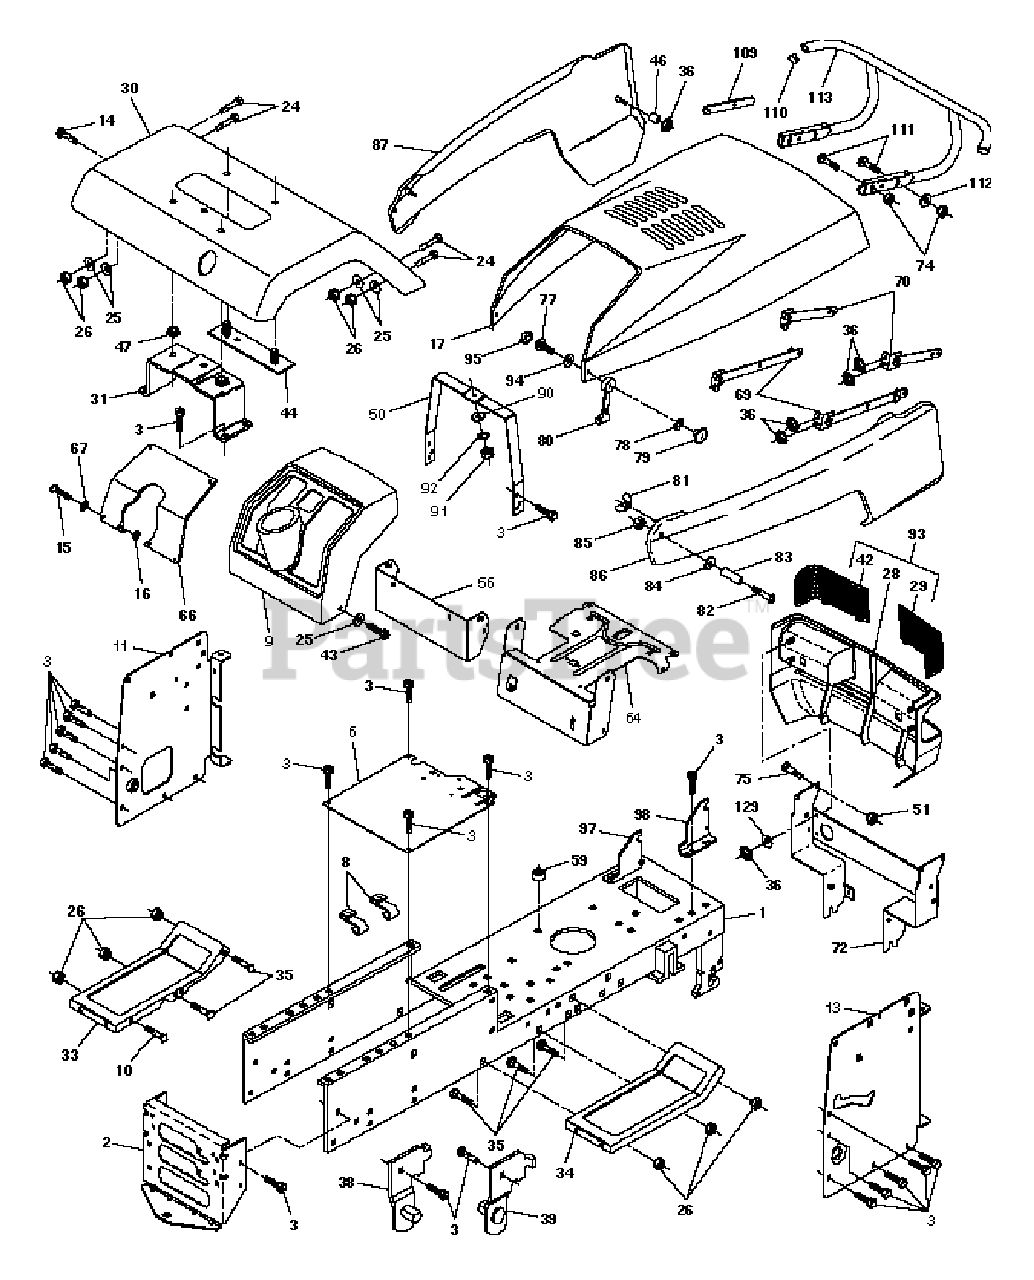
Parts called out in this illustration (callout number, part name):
1	Chassis WLDMT 11 Ga.
2	Drawbar
3	Screw, Thd., Roll. 3/8-16 x 3/4
8	Clip Insulator
10	Bolt, Carriage 3/8-16 UNC x 1
11	Dash Panel, LH
13	Dash Panel, RH
14	Screw Thdrol. 3/8-16 x 1/2
15	Screw, Machine 5/16-18 UNC x 3/4
16	Nut, Hex, Keps 5/16-18 UNC
24	Bolt, Hex, Fin. 3/8-16 UNC x 1
25	Washer 13/32 x 13/16 x 12 Gauge
26	Nut Lock Hex W/Ins. 3/8-16 UNC
28	Grille
29	Lens, Headlight, RH, Smoked
30	Fender
31	Bracket Fender
33	Footrest, LH
34	Footrest, RH
35	Bolt, Carriage 3/8-16 x 3/4
38	Pivot Bracket Assembly, Rear, LH
39	Pivot Bracket Assembly, Rear, RH
42	Lens, Headlight, LH, Smoked
43	Screw Thdrol 3/8-16 x 3/4 Ty-Tt
44	Strap Asm. Fender
47	Nut Push Nylon
50	Support, Dash
51	Nut Lock w/Ins. 1/4-20 UNC
56	Dash Extension
59	Bushing Snap Split
64	Dash, Lower
66	Plate, Dash
67	Washer 11/32 x 11/16 x 16 Gauge
69	Strap Assembly, Hinge, Rear
70	Strap Assembly, Hinge, Front
72	Support Assembly, Grille
74	Nut Crownlock 3/8-16 UNC
75	Bolt, Shoulder 1/4-20 UNC
77	Screw, Machine, Cross Pan Head #10-24 x 1/2
78	Washer, Lock #10
79	Nut, Weld
80	Latch, Chute
81	Nut Plastic Locking Wing 1/4-20
82	Screw, Machine, Cross Pan Head #10-24 x 1-1/4
83	Spacer, Split #10 x 3/4
84	Washer 7/32 x 1/2 x 18 Gauge
85	Nut, Hex, Keps #10-24 UNC
86	Side Panel, RH
87	Side Panel, LH
90	Washer 9/32 x 3/4 x 16 Gauge
91	Nut, Hex, Fin. 1/4-20 UNC
92	Washer, Lock,Hvy Helical 1/4
93	Grill Assembly
94	Washer, Cap
95	Cap, Black
97	Pivot Bracket Assembly, LH
98	Pivot Bracket Assembly, RH
109	Bracket Extension Bumper
110	Plug Plastic
111	Bolt, Carriage 3/8-16 x 1-1/4
112	Washer 13/32 x 13/16 x 16 Ga.
113	Bumper Asm
129	Washer 9/32 x 5/8 x 16 Ga.
